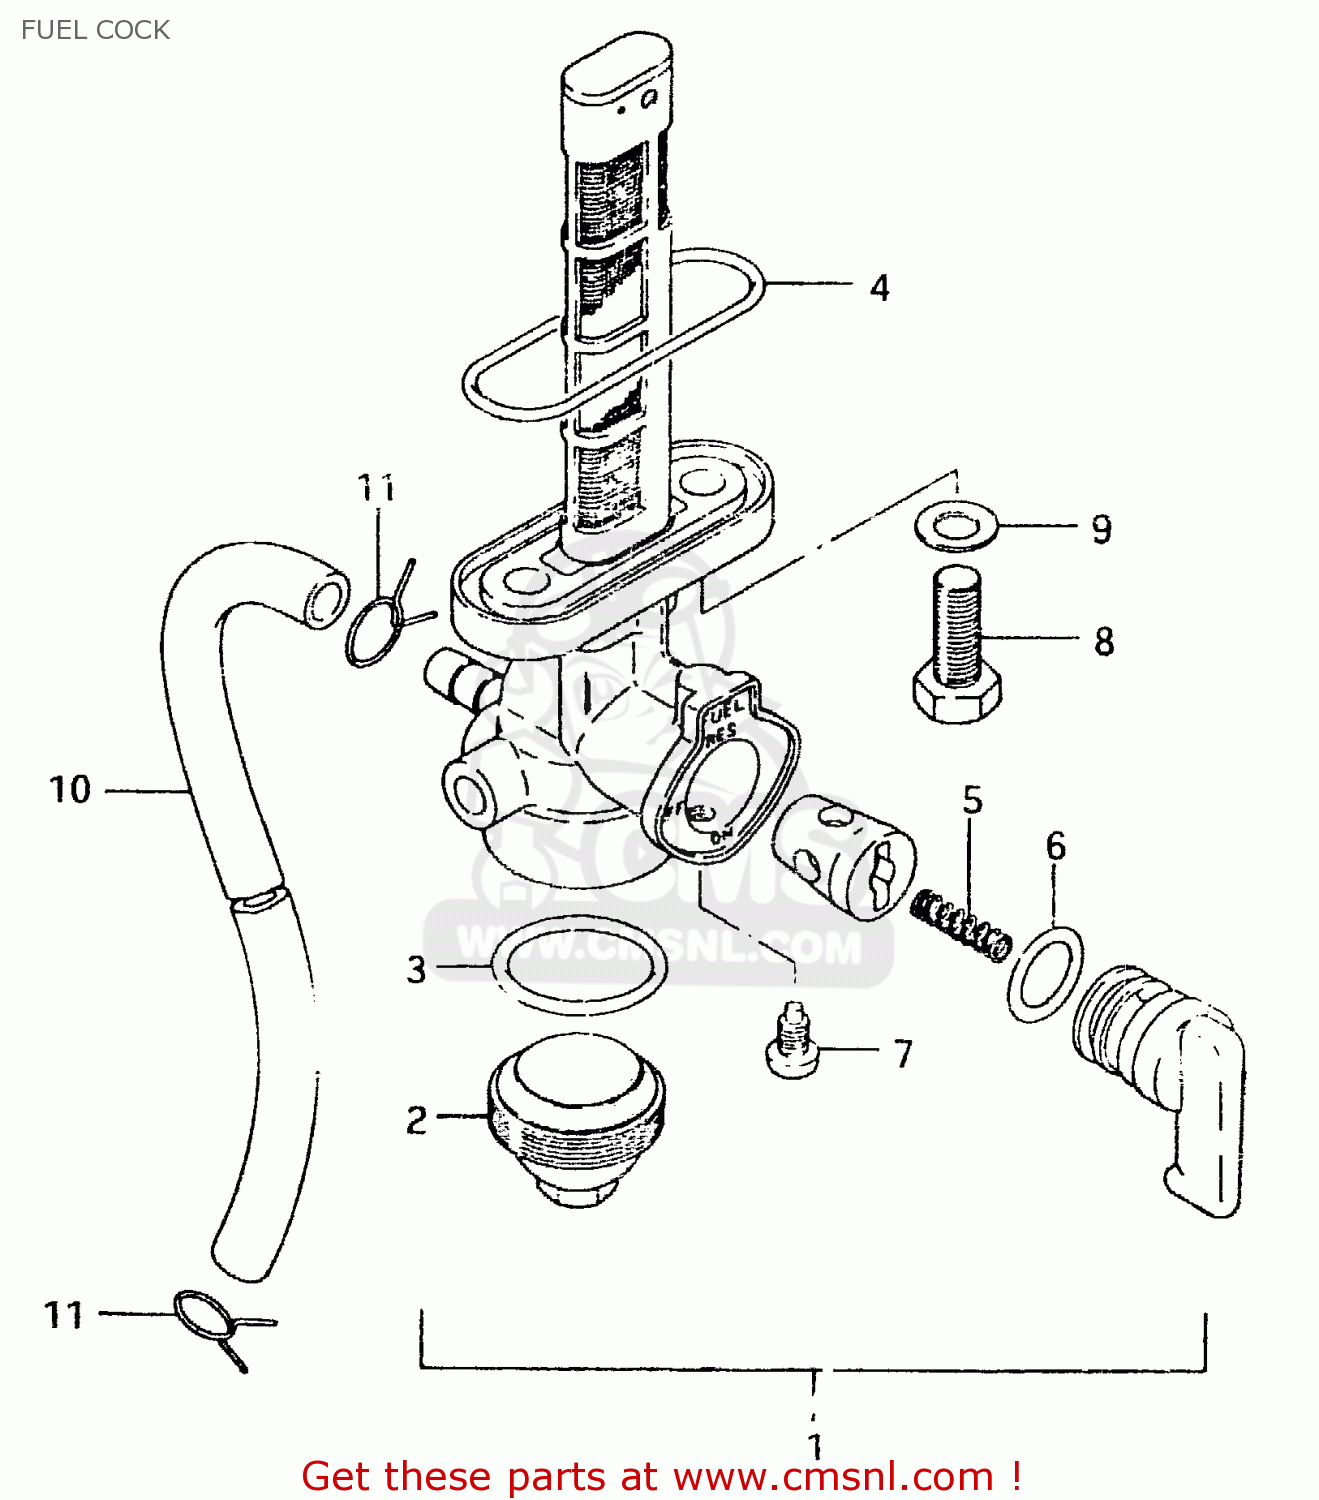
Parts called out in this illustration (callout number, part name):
1	COCK ASSEMBLY,FUEL
2	CUP,STRAINER
3	GASKET,FILTER (NAS)
4	O RING,FUEL COCK
5	SPRING
6	O-RING
7	SCREW
8	BOLT(6X20)
9	GASKET
10	HOSE
11	CLIP
